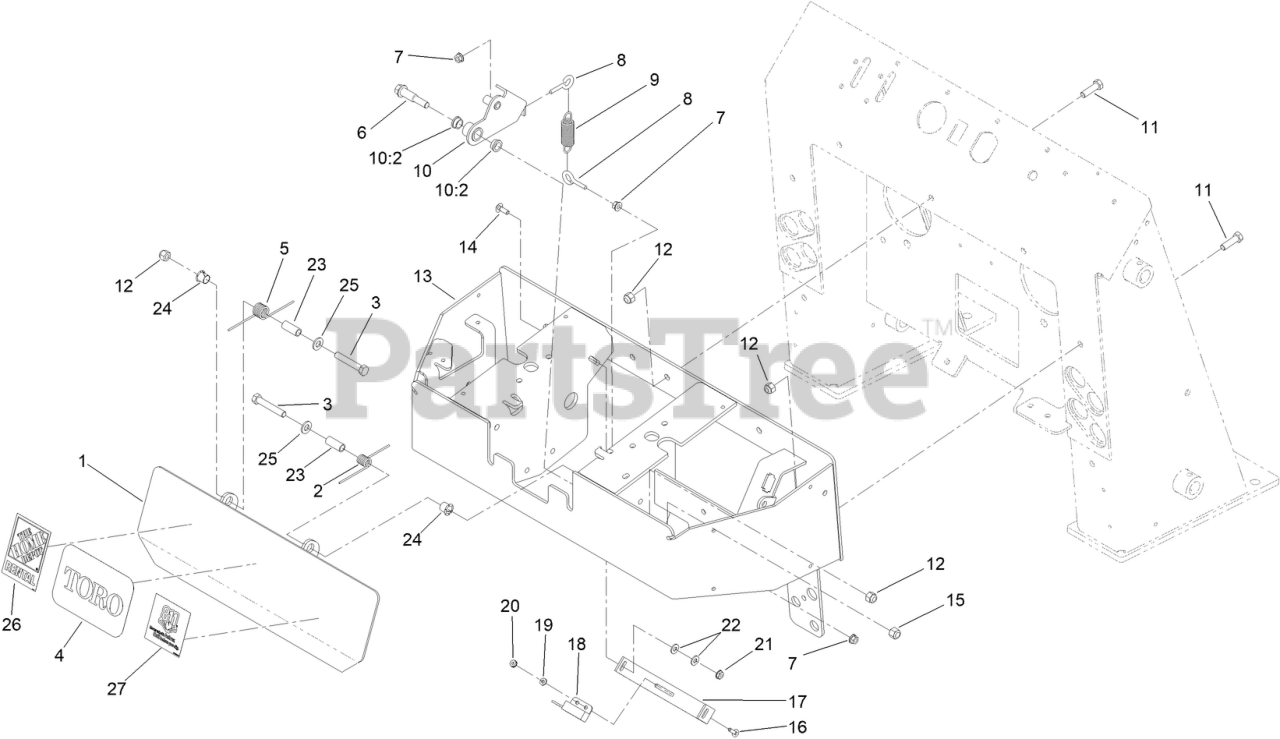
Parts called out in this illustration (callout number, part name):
1	PLATE-REVERSE
2	SPRING-TORSION, LH
3	SCREW-HH
5	SPRING-TORSION, RH
6	BOLT-SHOULDER
7	NUT-HHF
8	BOLT-EYE
9	SPRING-EXTENSION
10	NEUTRAL CENTERING LEVER ASM
10:2	BUSHING-FLANGE
11	SCREW-HH
12	NUT-LOCK, NI
13	PANEL-CONTROL
14	BOLT-CARR
15	NUT-LOCK
16	SCREW-CARR
17	PLATE-SWITCH
18	SWITCH-PROXIMITY
19	WASHER-FLAT
20	NUT-KEPS
21	NUT-KEPS
22	WASHER-FLAT
23	SPACER-SPRING
24	BUSHING-NYLINER
25	WASHER-FLAT
26	DECAL- RHVSG3X4
27	DECAL-CPER0811
